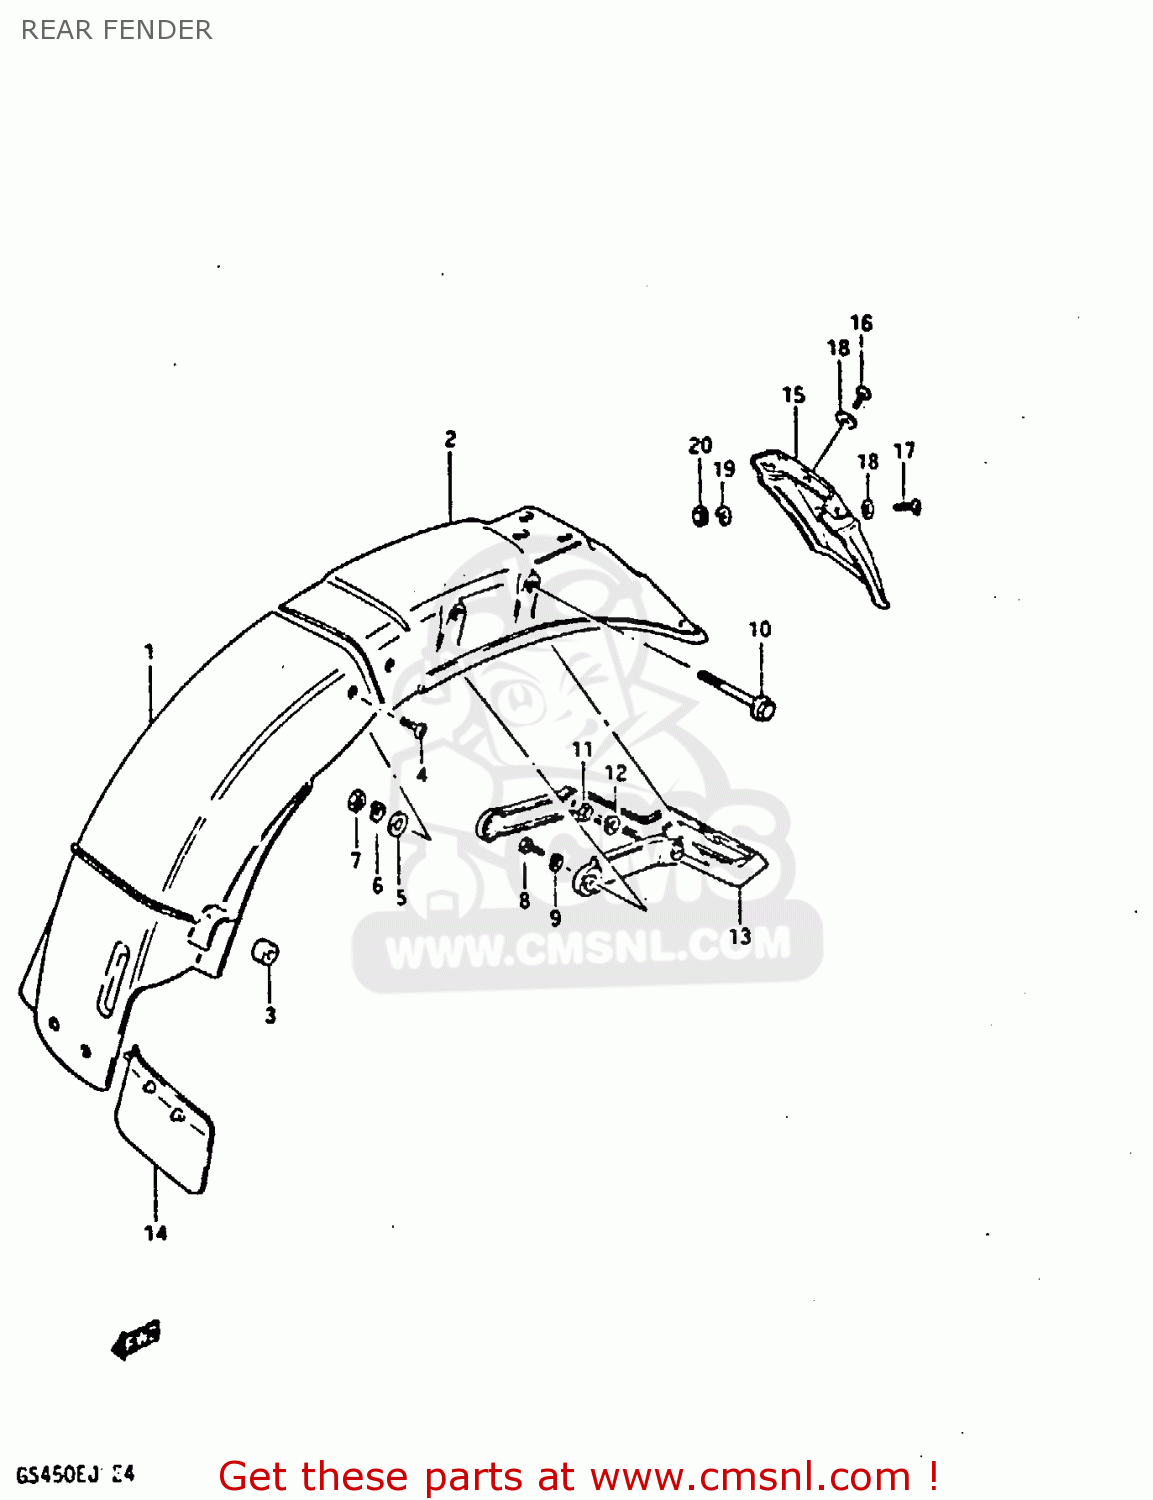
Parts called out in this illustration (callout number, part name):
1	FENDER,REAR
2	BODY,RR FENDER RR
3	CUSHION
4	SCREW
5	WASHER (5.5X16X1.2)
6	LOCK WASHER
7	NUT
8	BOLT
9	WASHER,LOCK
10	BOLT
11	NUT
12	LOCK WASHER
13	REINFORCEMENT,REAR FENDER
14	GUIDE,RR FENDER MUD
15	EXTENTION, REAR FENDER
16	SCREW 6X12
17	SCREW
18	WASHER(6.5X18X1)
19	WASHER,LOCK
20	NUT 6MM
